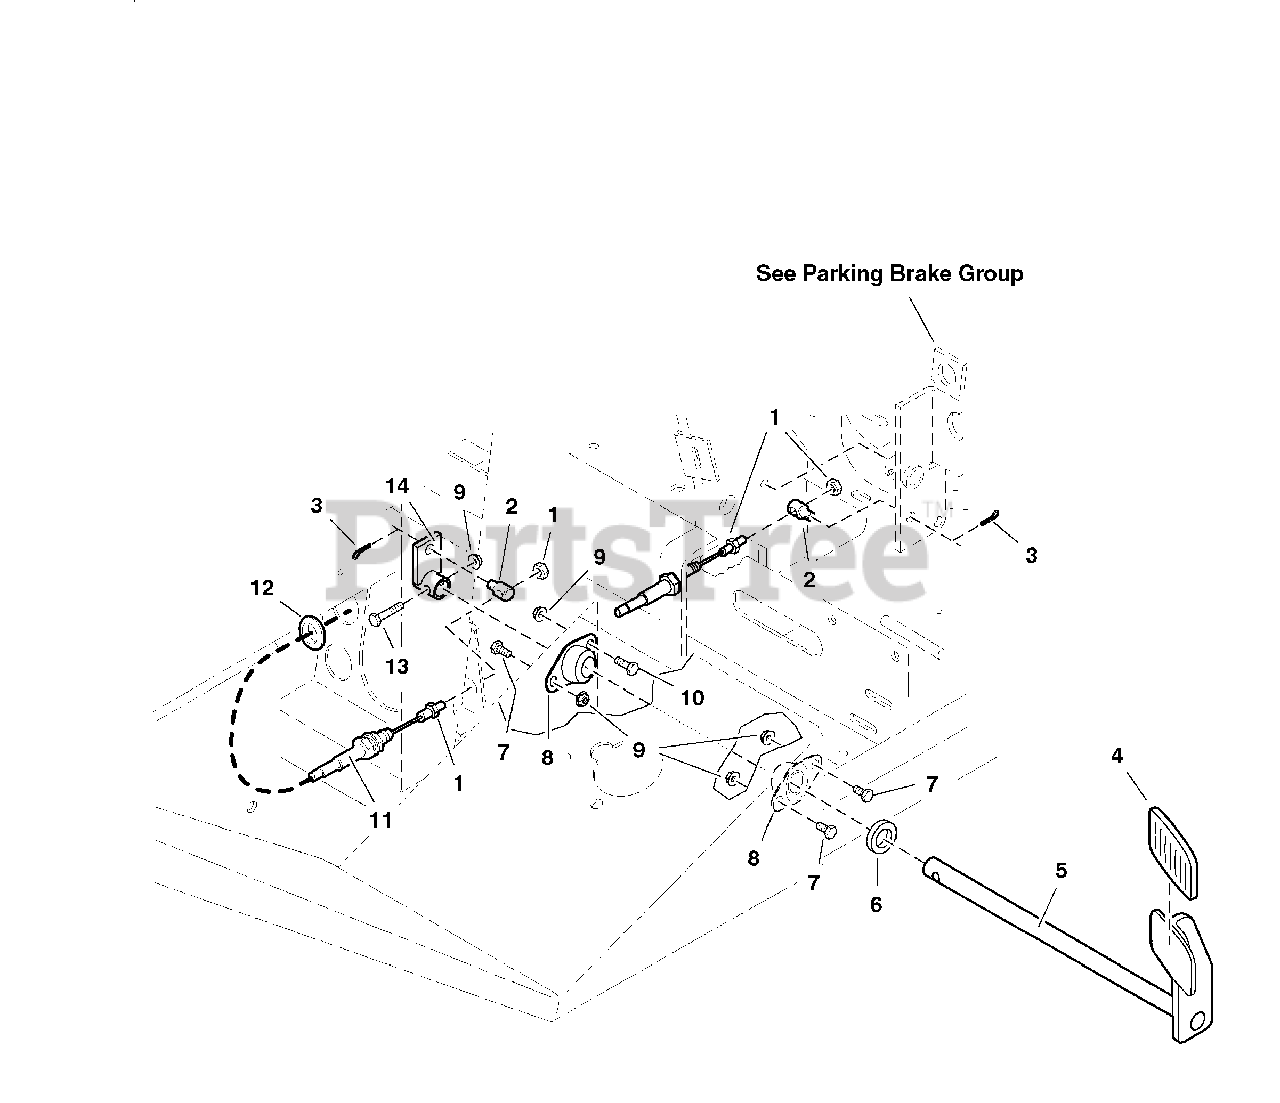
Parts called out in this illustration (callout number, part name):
1	NUT, Hex, 5/16-24
2	ADJUSTER, Brake Linkage
3	PIN, Cotter
4	FOOT PAD
5	BRAKE PEDAL SHAFT
7	CAPSCREW, Hex Hd, 1/4-20 x 3/4
8	BEARING, Flange
9	NUT, Hex, Serrated Flange, 1/4-20
10	BOLT, 1/4-20 X 1", GD
11	BRAKE CABLE
13	CAPSCREW, Hex Hd, 1/4-20 x 1-1/2
